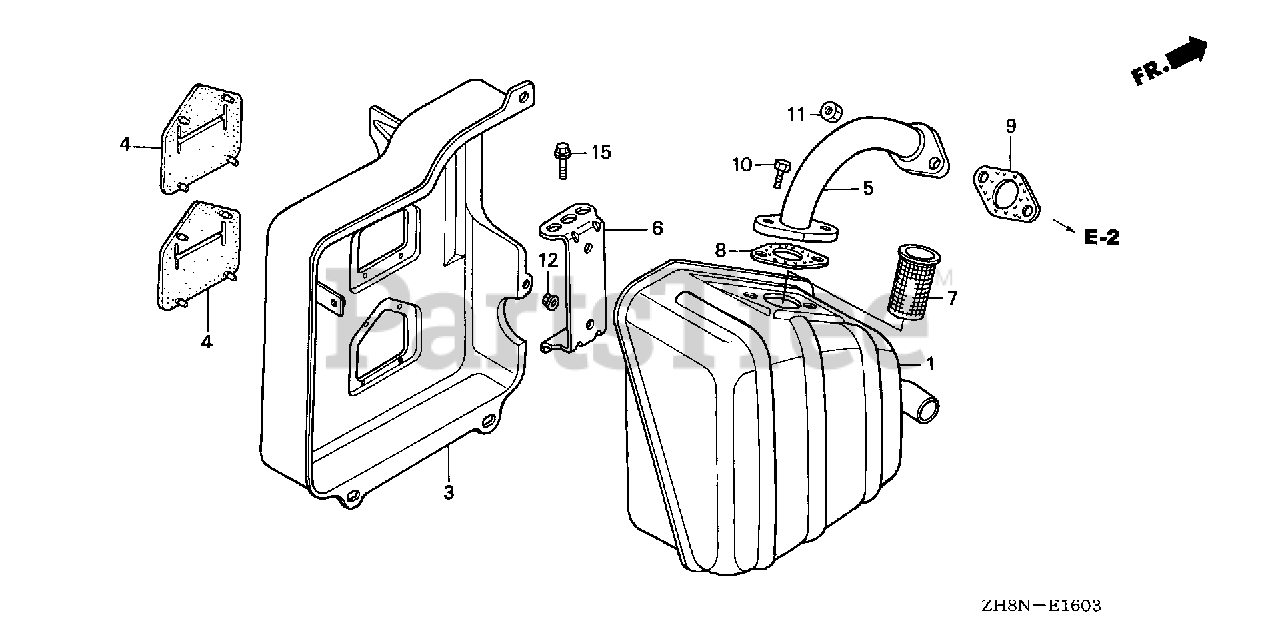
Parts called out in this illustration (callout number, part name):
1	MUFFLER
3	PROTECTOR, MUFFLER (INNER)
4	SEAL, MUFFLER PROTECTOR
5	PIPE, EX.
6	STAY, MUFFLER
7	ARRESTER, SPARK
8	GASKET, MUFFLER
9	GASKET, MUFFLER
10	BOLT, HEX. (8X20)
11	NUT, HEX. (8MM)
12	NUT, FLANGE (6MM)
15	BOLT, FLANGE (8X20)
